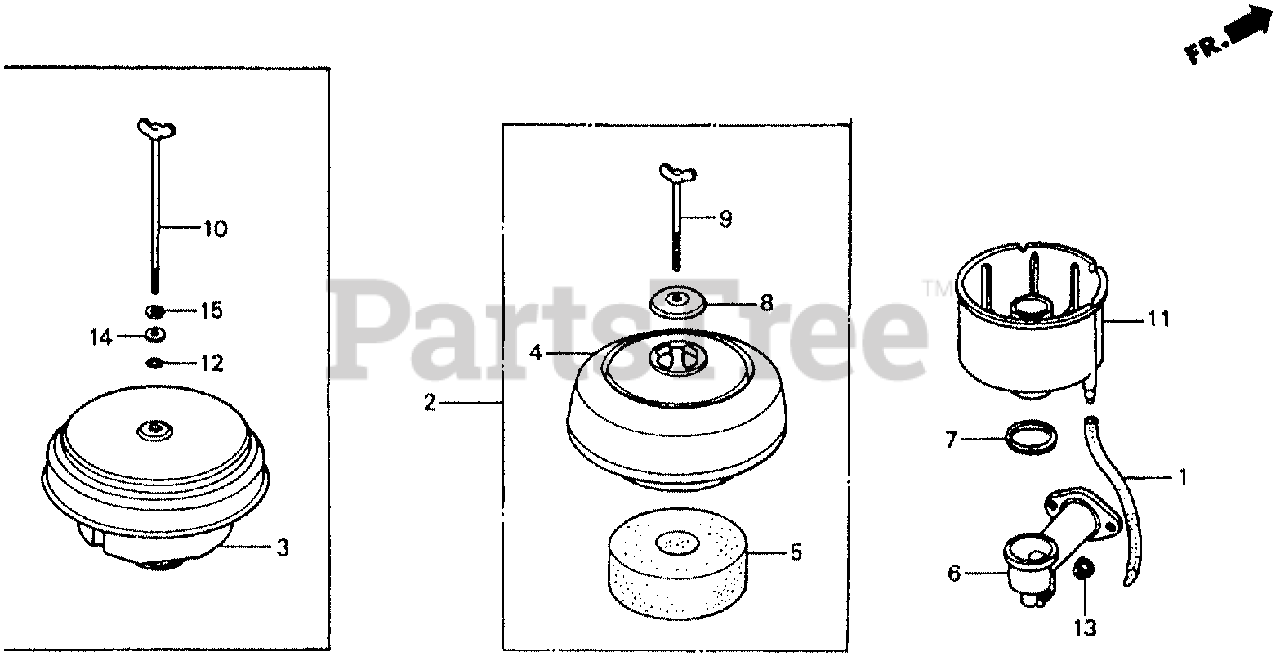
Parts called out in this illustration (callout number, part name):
1	TUBE, BREATHER
2	BODY KIT, AIR CLEANER (NOT AVAILABLE)
3	AIR CLEANER ASSY., OIL BATH
4	BODY, AIR CLEANER
5	ELEMENT, AIR CLEANER
6	ELBOW, AIR CLEANER
7	GASKET, IN. ELBOW
8	CAP, AIR CLEANER
9	BOLT, AIR CLEANER
10	BOLT, AIR CLEANER
11	PAN, CLEANER OIL
12	O-RING (4.9X2.5)
13	NUT, FLANGE (6MM)
14	WASHER, PLAIN (6MM)
15	WASHER, SPRING (6MM)
